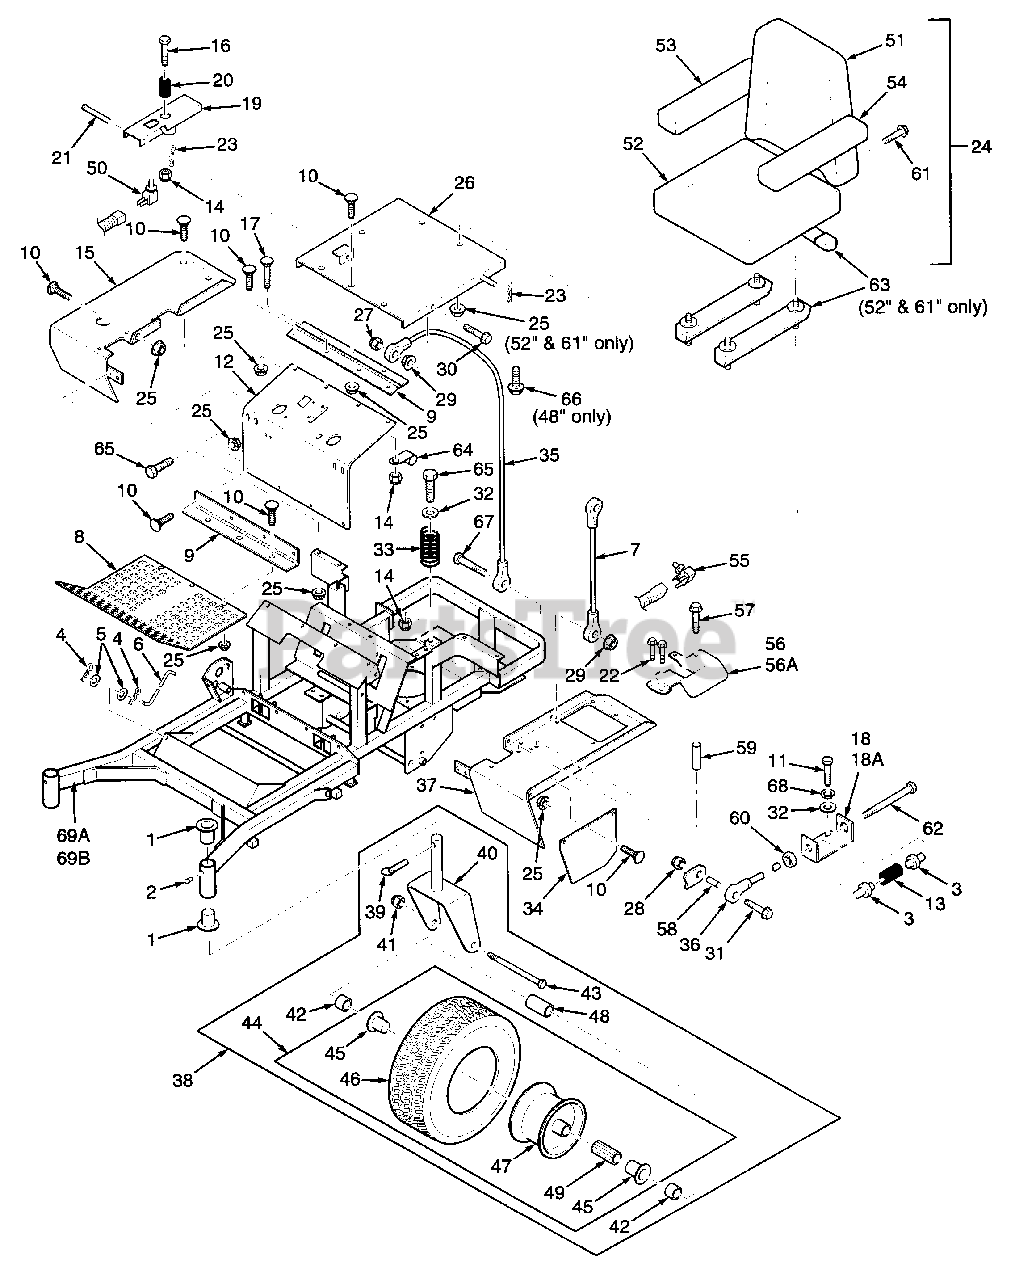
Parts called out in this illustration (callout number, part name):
1	Bushing
2	Grease Fitting
3	Bushing, Spring Keeper
4	Hair Pin, .08 Diameter x 1-3/16"
5	Flatwasher, 3/8" (.391 x .738 x .105)
6	Rod, Foot Plate Latch
7	Cable, Seat Stop
8	Foot Plate
9	Hinge
10	Bolt, Carriage 5/16-18 x 3/4"
11	Bolt, Serrated Flange Hex Head 5/16-18 x 3/4"
12	Kick Plate
13	Neutral Return Spring
14	Nut, Elastic Stop 5/16-18
15	Fender Assembly, RH (with decal)
16	Bolt, Hex Head 5/16-18 x 3-3/4"
17	Bolt, Carriage 5/16-18 x 1"
18	Retainer, Neutral Spring, LH
18A	Retainer, Neutral Spring, RH
19	Seat Switch Bracket
20	Spring
21	Clevis Pin
22	Bolt, Serrated Flange Hex Head 5/16-18 x 1/2"
23	Hair Pin, Cotter
24	Seat Assembly
25	Nut, Serrated Flange Hex 5/16-18
26	Seat Base
27	Nut, Elastic Stop 1/4-20
28	Nut, Elastic Stop 3/8-16
29	Nut, Serrated Flange Hex 1/4-20
30	Bolt, Serrated Flange Hex Head 1/4-20 x 1"
31	Bolt, Hex Head 3/8-16 x 2-1/2"
32	Flatwasher, 5/16" (.313 x .875 x .083)
33	Seat Spring
34	Fender Panel, LH
35	Cable, Seat Stop
36	Ball Joint, Neutral
37	Fender, LH
38	Caster Wheel Yoke Assembly
39	Quick Pin
40	Caster Wheel Yoke
41	Nut, Elastic Stop 1/2-13
42	Spacer
43	Bolt, Hex Head 1/2-13 x 6-1/2"
44	Wheel Assembly, Complete
45	Retainer
46	Tire Only
47	Rim Only
48	Sleeve
49	Roller Bearing
50	Seat Switch
51	Seat, Back Cushion
52	Seat, Bottom Cushion
53	Arm Pad, RH
54	Arm Pad, LH
55	Neutral Interlock Switch
56	Neutral Lock Bracket, RH
56A	Neutral Lock Bracket, LH
57	Bolt, Serrated Flange Hex Head 5/16-18 x 2-3/4"
58	Spacer, Neutral Spring
59	Spacer, Neutral Lock Bracket
60	Nut, Hex 3/8-24 UNF
61	Bolt, Hex Head w/Washer, 1/4-20 x 3/4"
62	Bolt, Hex Head 3/8-24 x 6-1/2", UNF
63	Seat Adjustment, Track Set
64	Cable Clamp, .50 ID
65	Bolt, Hex Head 5/16-18 x 1"
69A	Main Frame Assy.
69B	Main Frame Assy.
